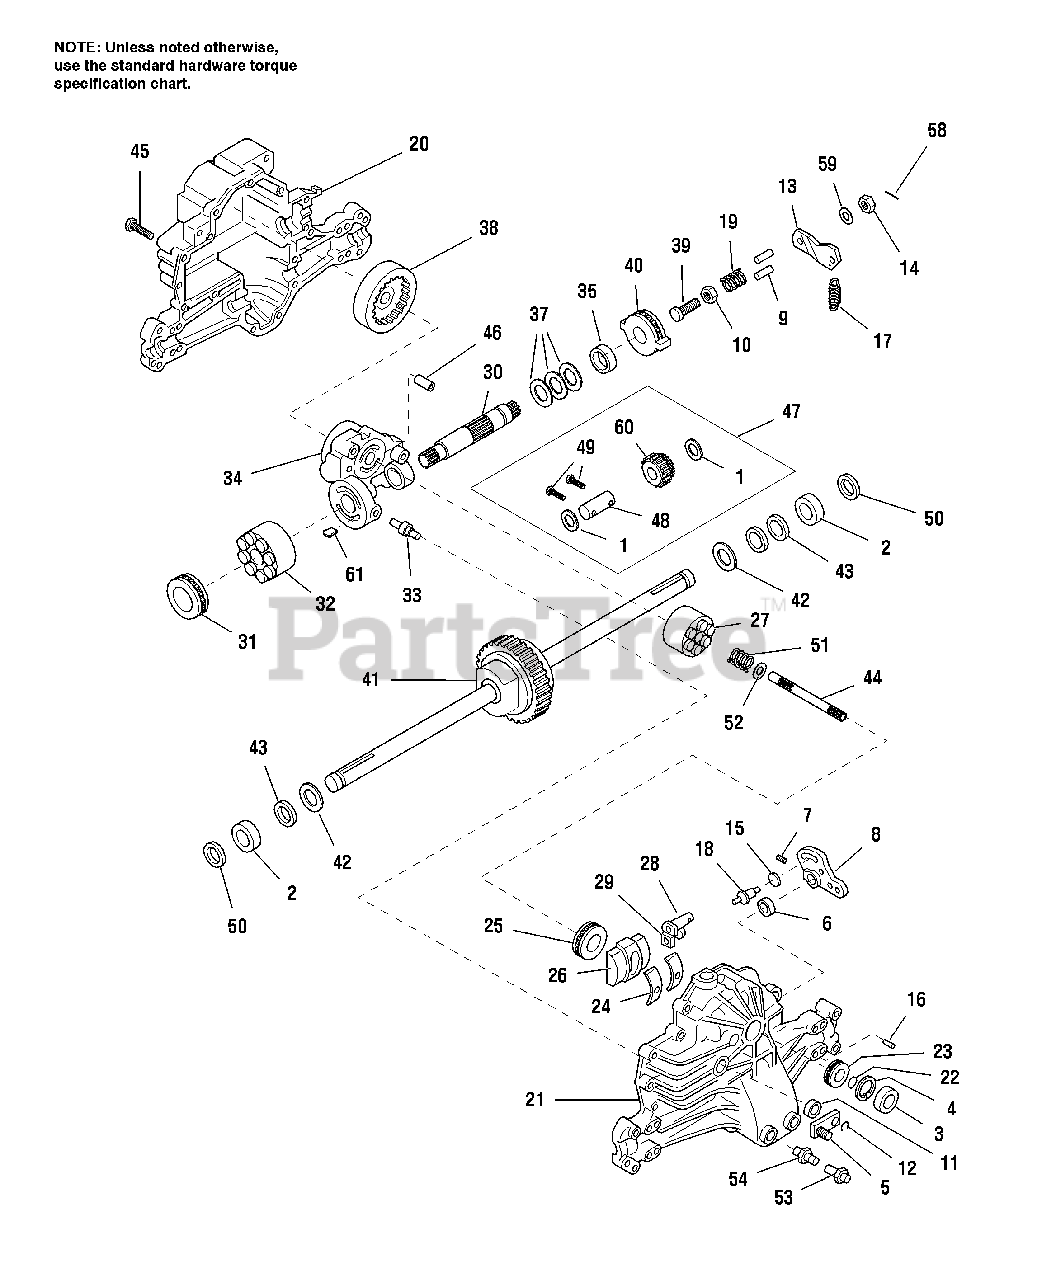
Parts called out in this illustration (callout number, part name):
1	WASHER, 7/16 x 1 x 1/2
2	BALL BEARING
4	RETAINING RING
5	ARM, Bypass
8	ARM, Control
9	PIN, Actuating
10	NUT, Hex, Lock, 5/16-24
12	RETAINING RING
13	ARM, Actuating
14	CASTLE NUT, 5/16-24
15	PUCK, Dampener
17	SPRING, Extension
18	STUD, 5/16-24
19	SPRING, Compression
20	HOUSING, Lower
21	HOUSING, Upper
23	BALL BEARING, Shaft
24	BEARING, Cradle
25	BEARING, Thrust
27	BLOCK, Cylinder
28	ARM, Trunnion
29	GUIDE, Slot
30	SHAFT, Motor
31	BEARING, Thrust
32	BLOCK, Cylinder
33	ACTUATOR, Bypass
34	CENTER SECTION ASSY.
37	WASHER, 17/64 x 23/64 x 1
38	ELEMENT, Oil Filter
39	BOLT, 5/16-18 x 1-3/4
40	BRAKE ROTOR/STATOR KIT
41	DIFFERENTIAL ASSY.
42	WASHER, 3/4 X 1-1/2 X 1/32
43	SEAL, 3/4 X 1-1/4 X 1/4
44	SHAFT, Input
45	BOLT, 1/4-20 x 1-3/8
46	PIN, 1/2 O.D. x 7/16 I.D. x 3/4
47	JACK SHAFT/PINION GEAR ASSY.
49	CAPSCREW, 6 mm x 13/64
50	SEAL, Wiper
51	SPRING, Block
52	WASHER, Block Thrust
53	VENT CAP ASSY.
54	FITTING & O-RING ASSY.
58	COTTER PIN
59	WASHER, 7/16 x 7/8 x 51/64
61	BYPASS PLATE
